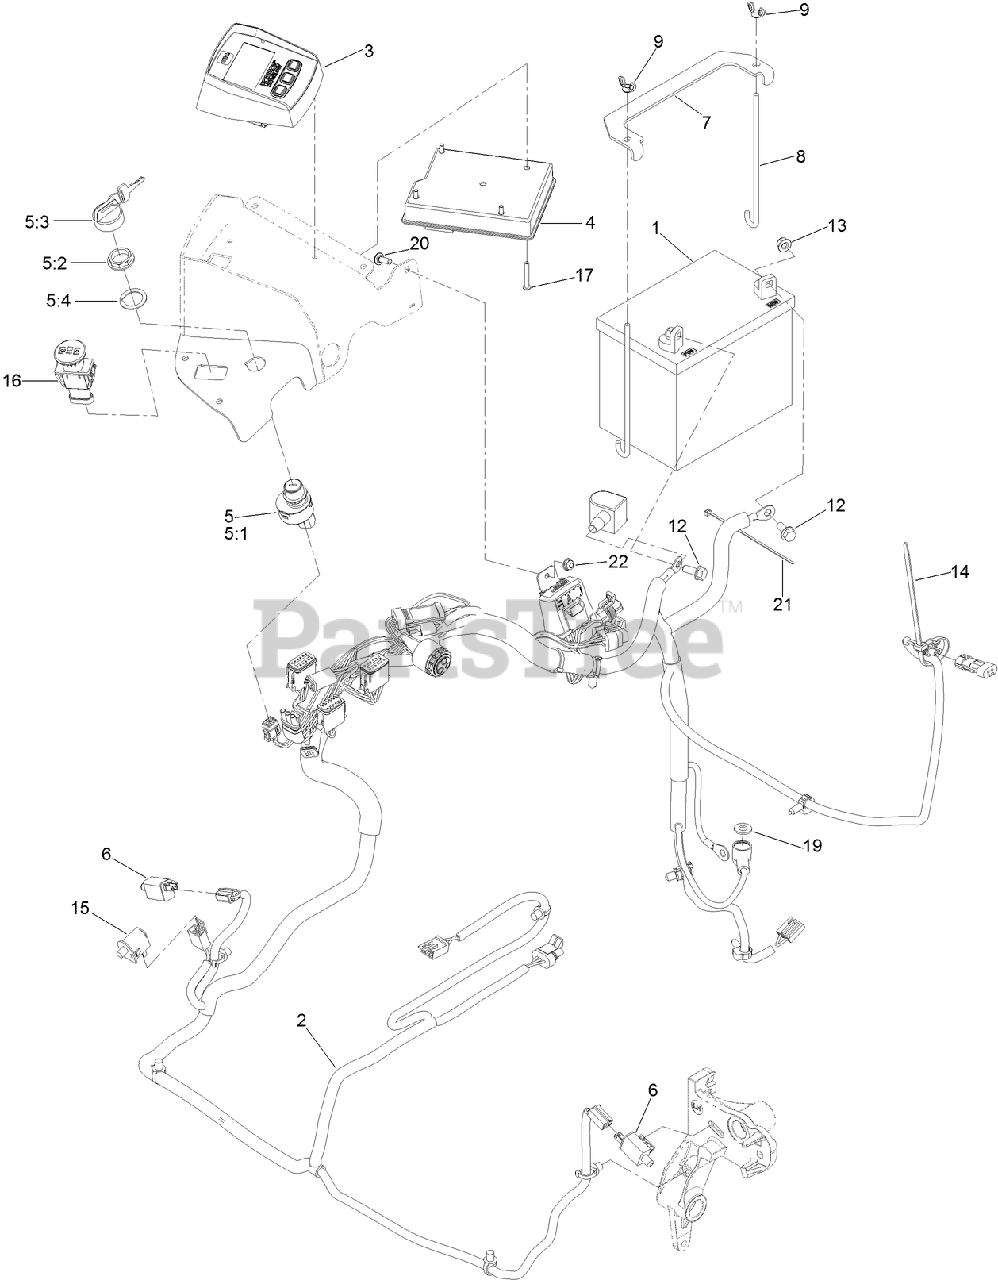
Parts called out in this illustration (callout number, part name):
1	BATTERY (340 CCA, WET)
2	HARNESS-WIRE
3	MODULE-HORIZON
4	MODULE-MCU
5	IGNITION SWITCH ASM
5:1	Deck ASM
5:2	NUT-MOUNTING
5:3	IGNITION KEY SET
5:4	WASHER-BACKUP
6	SWITCH
7	STRAP-TIE DOWN, BATTERY
8	BOLT-HOLDDOWN
9	WINGNUT
12	SCREW-HH
13	NUT-HF, NI
14	TIE-PLASTIC
15	SWITCH-BAIL
16	SWITCH-PTO, SEALED
17	SCREW-PPH
19	WASHER-FLAT
20	BOLT-CARR
21	TIE-CABLE
22	NUT-HF
